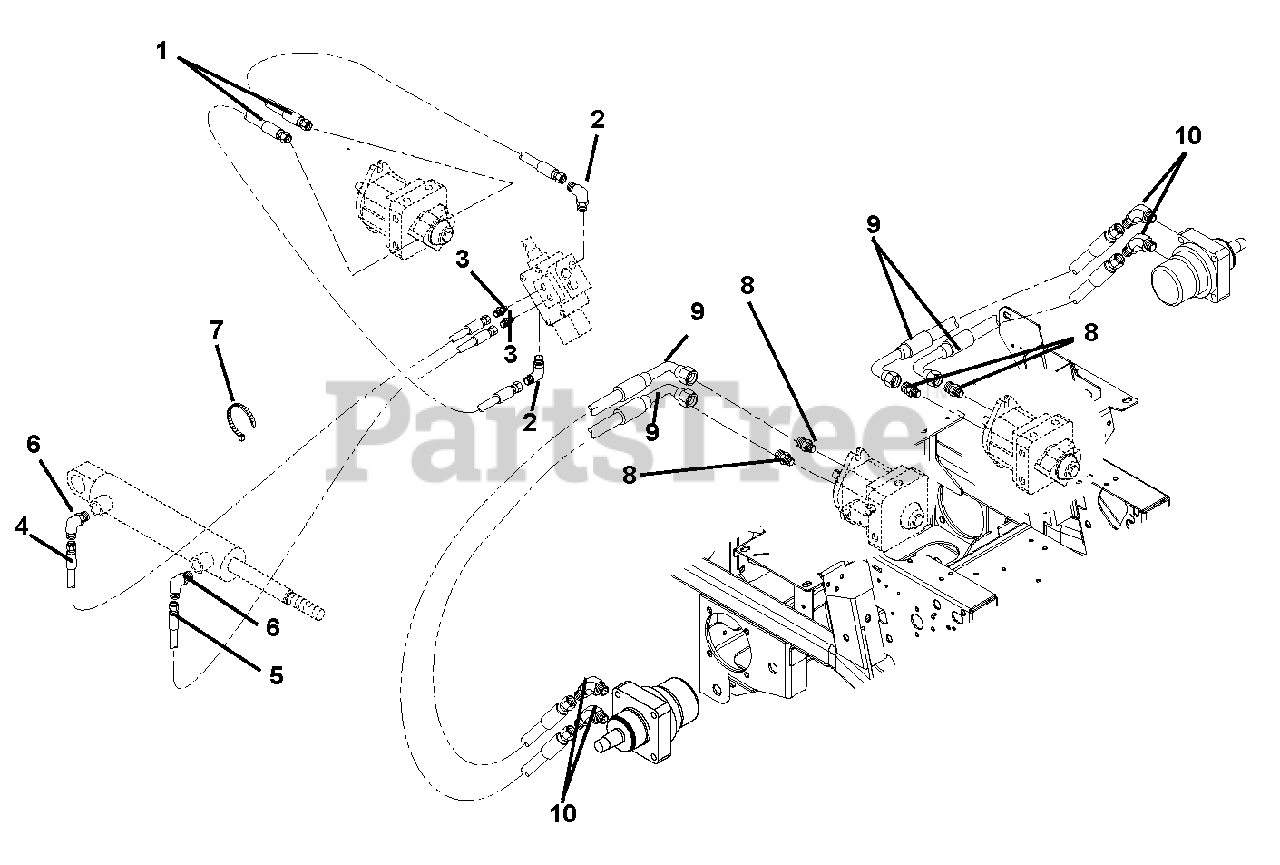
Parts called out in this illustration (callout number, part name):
1	Hose, Hydraulic
2	Hydraulic, Fitting Elbow
4	Hose, Hydraulic
5	Hose, Hydraulic
6	Fitting, Hydraulic
7	Cable Tie
8	Adapter, Face Seal 8 x 8 .50 O-Ring
9	Hose, Hydraulic .50
10	Adapter-Hydraulic Steel .875 to .75
